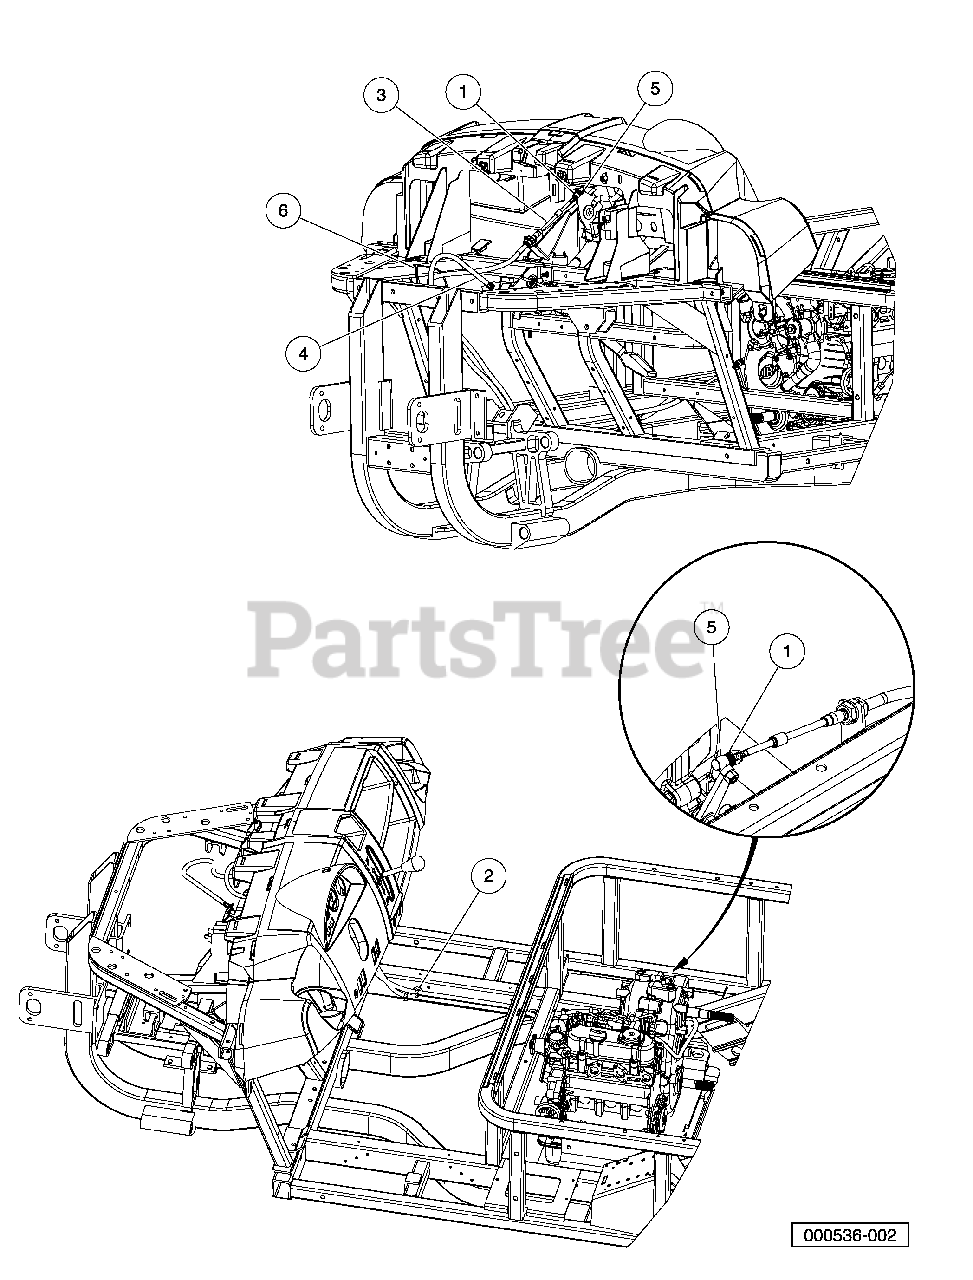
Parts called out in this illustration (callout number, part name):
1	Nut, 1/4-28 Hex Jam
2	Clip, Brake Line
3	Cable, Transmission Shift
4	Cable, Accelerator, Diesel
5	Joint, Ball, .346 Dia
6	Tie Wrap, 8" Nylon
